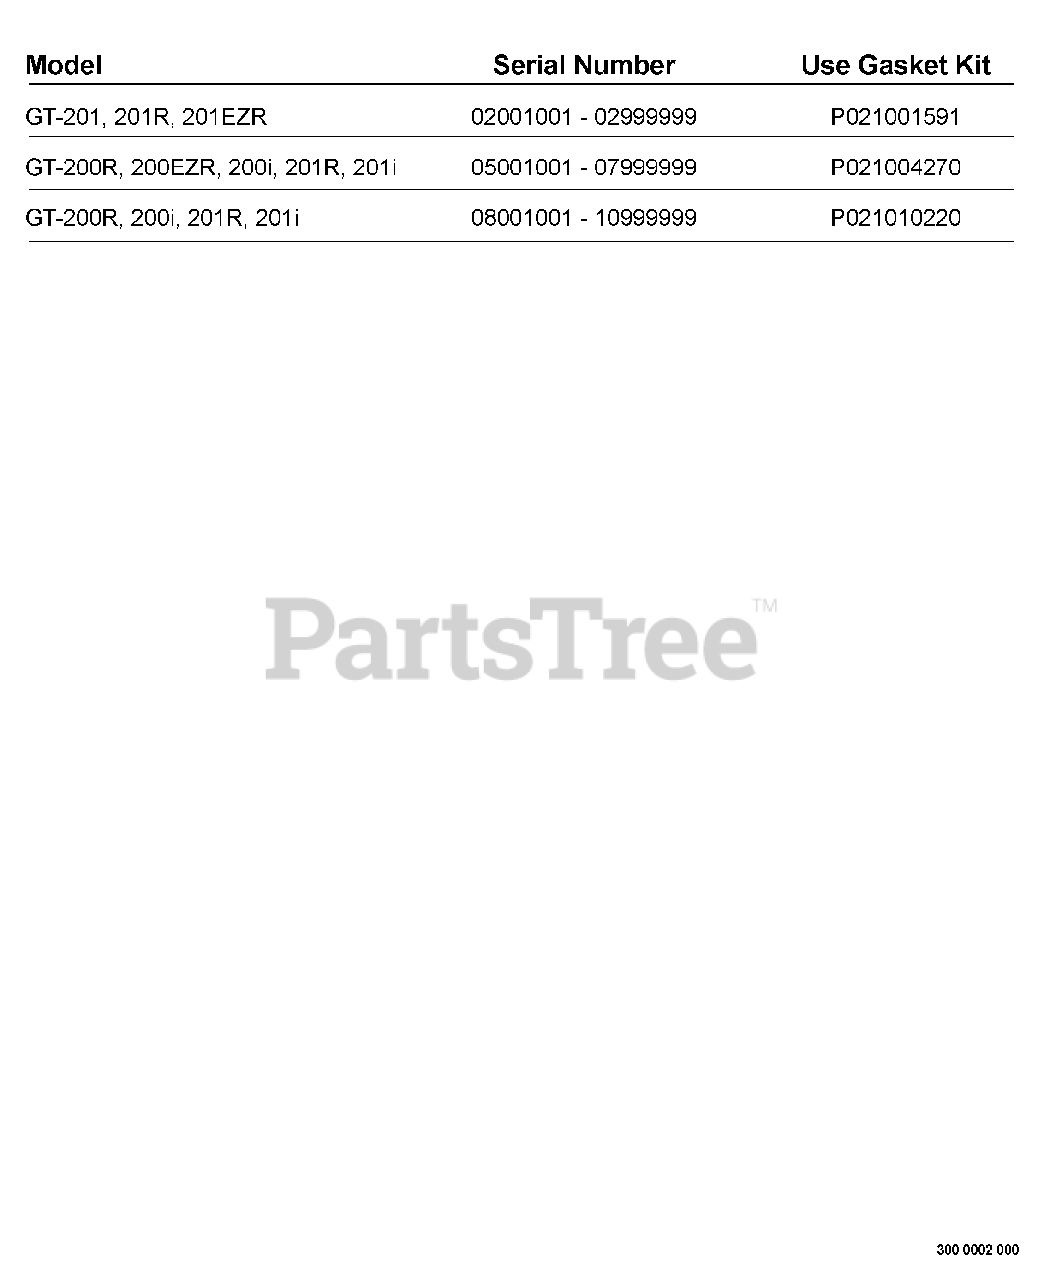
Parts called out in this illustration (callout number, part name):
1	GASKET KIT
2	GASKET KIT
3	GASKET KIT
